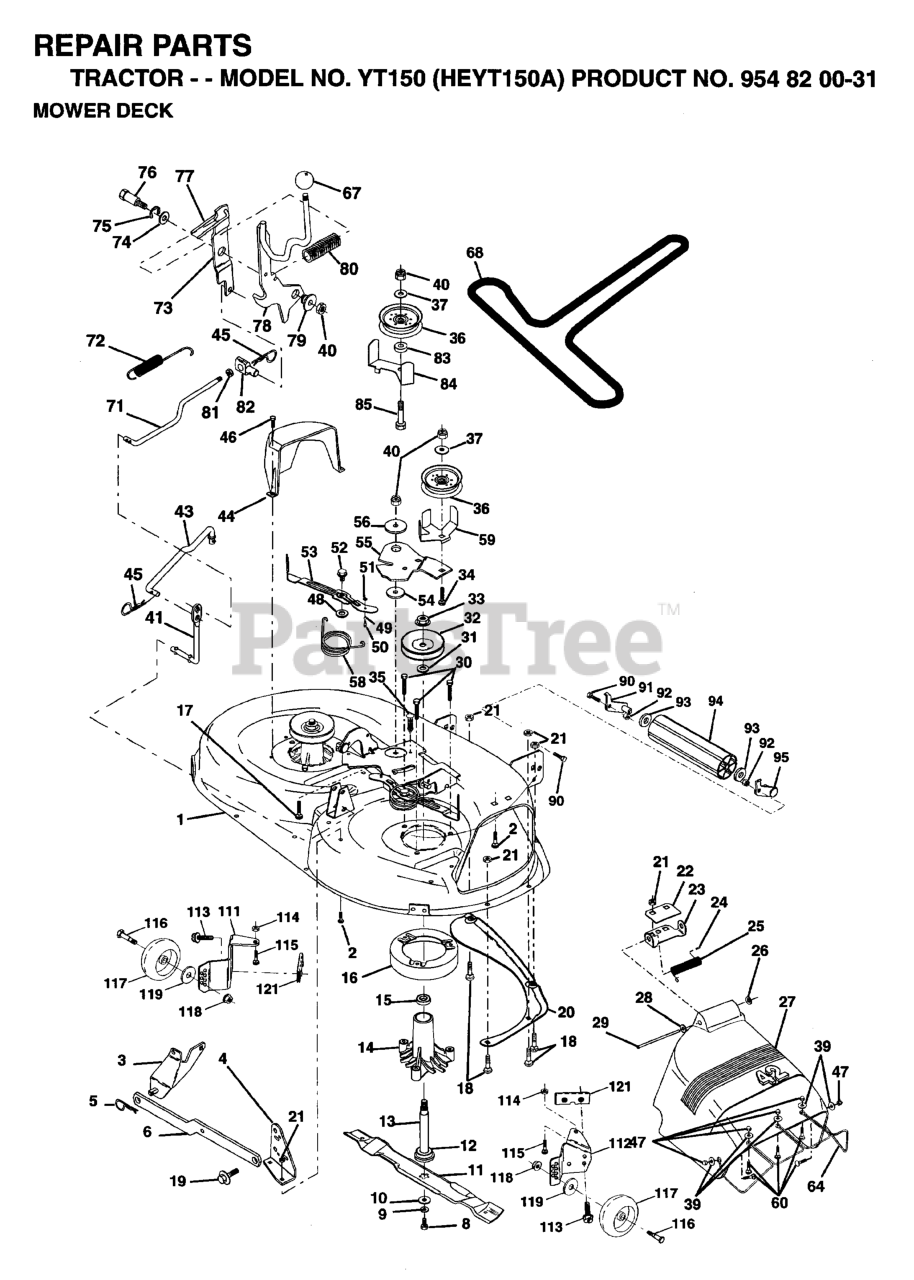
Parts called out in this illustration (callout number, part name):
1	DECK 42"
2	RP BOLT 5/16-18 X3/4 ZN/YEL GR
3	BRKT ASM SWAY BAR
4	BRKT DECK SW BAR
5	RETAINER-SPRNG RB
6	REAR SUSP ARM
8	BLADE BOLT
9	LOCKWASHER
10	WASHER.BLADE
11	Blade Mower 42" High Perf.
12	BEARING.BALL.#6204.(MANDREL)
13	SHAFT ASM VENT
14	HOUSING.MANDREL.VENTED (MACHD)
16	STRIPPER
17	BOLT
18	BOLT
19	BOLT SHD 5/16-18
20	BAFFLE
21	LOCKNUT
22	STIFFENER BRACKET
23	DEFLECTOR BRACKET
24	CAP-SLEEVE LT
25	SPRING TORSION
26	NUT PUSH M
28	Washer 11/32 x 5/8 x 16 Ga SD
29	ROD.HINGE
30	SCREW
31	WASHER
32	MANDREL PULLEY
33	NUT
35	FASTENER.XMAS.TREE
36	FLAT IDLER PULLEY
37	WASHER
39	REPL BY 734 11 46-01
43	CLUTCH ROD
44	GUARD MANDREL LH BLACK
45	RETAINER M
46	SCREW.1/4-20X5/8
47	NUT
49	CAM FOLLOWER
52	BOLT.SHOULDER.5/16-18
53	ARM
54	HARDENED WASHER
55	IDLER ARM
56	SPACER RETAINER
59	GUARD, BELT
60	SCREW
67	KNOB T (1/2-HOLE)
68	V-BELT TRIPATH
71	CLUTCH ROD
72	RETURN SPRING
73	ARM CLUTCH SECONDARY
77	KEEPER SPRING
78	CLUTCH ARM
79	BUSHING.FLANGE.E-RING.GROOVE
80	SPRING
81	NUT
82	TRUNNION.ADJUSTABLE.3/8-16
84	KEEPER BELT
85	BOLT
90	BOLT
91	BRACKET LH (A)
92	NUT
93	Washer 1 17/32 X 7/8 X 16 Ga
94	NOSE ROLLER
95	BRACKET RH (B)
111	BRACKET
112	BRACKET
113	SCREW.THDROL.5/16-18X3/4.TTY
114	NUT
115	BOLT.CARR.5/16-18X1/2
116	BOLT, SHOULDER
117	WHEEL GAGE DONUT
118	LOCKNUT
119	WASHER.5/16.FLAT.STE.STD.
121	BRACKET.EXTRUDED.GAGE.WHEEL
